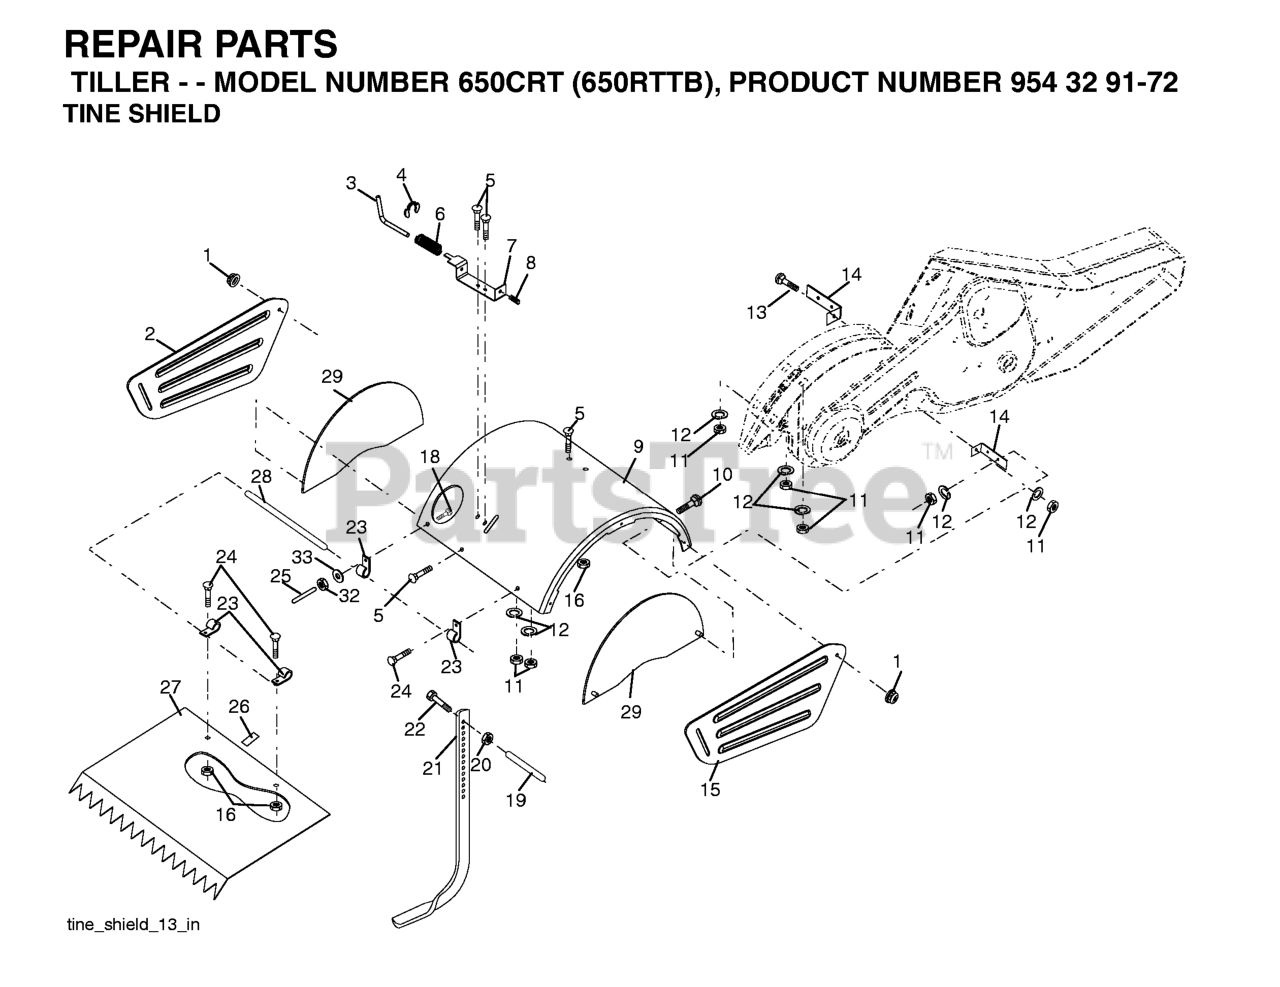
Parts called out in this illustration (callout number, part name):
1	NUT LOCK HEX FLANGE 5/16-18
2	SHIELD
3	STAKE PIN TI
4	RING, KLIP
5	BOLT, RDHD SQNK 5/16-18 X 3/4
7	BRACKET.LATCH.STAKE.3.20.BLACK
8	SPRING CRT
9	SHIELD
10	BOLT
11	NUT
12	WASHER.LOCK.HVY.HLCL.SPR.5/16
13	BOLT.CARRIAGE.5/16-18
14	BRACKET.TINE.SHIELD.TILLER.BLA
15	SIDE SHIELD RH
16	NUT T
20	NUT.HEX.3/8-16UNC
21	STAKE.DEPTH.16.CRT.BLACK
22	BOLT.375-16
24	BOLT
25	VINYL CAP TI
26	PAD IDLER TI
27	SHIELD LEVELING
28	PIN.HINGE.TILLER
29	SIDE SHIELD
30	LOCKNUT-FLANGE 5/16-18
32	NUT
33	LOCKWASHER
